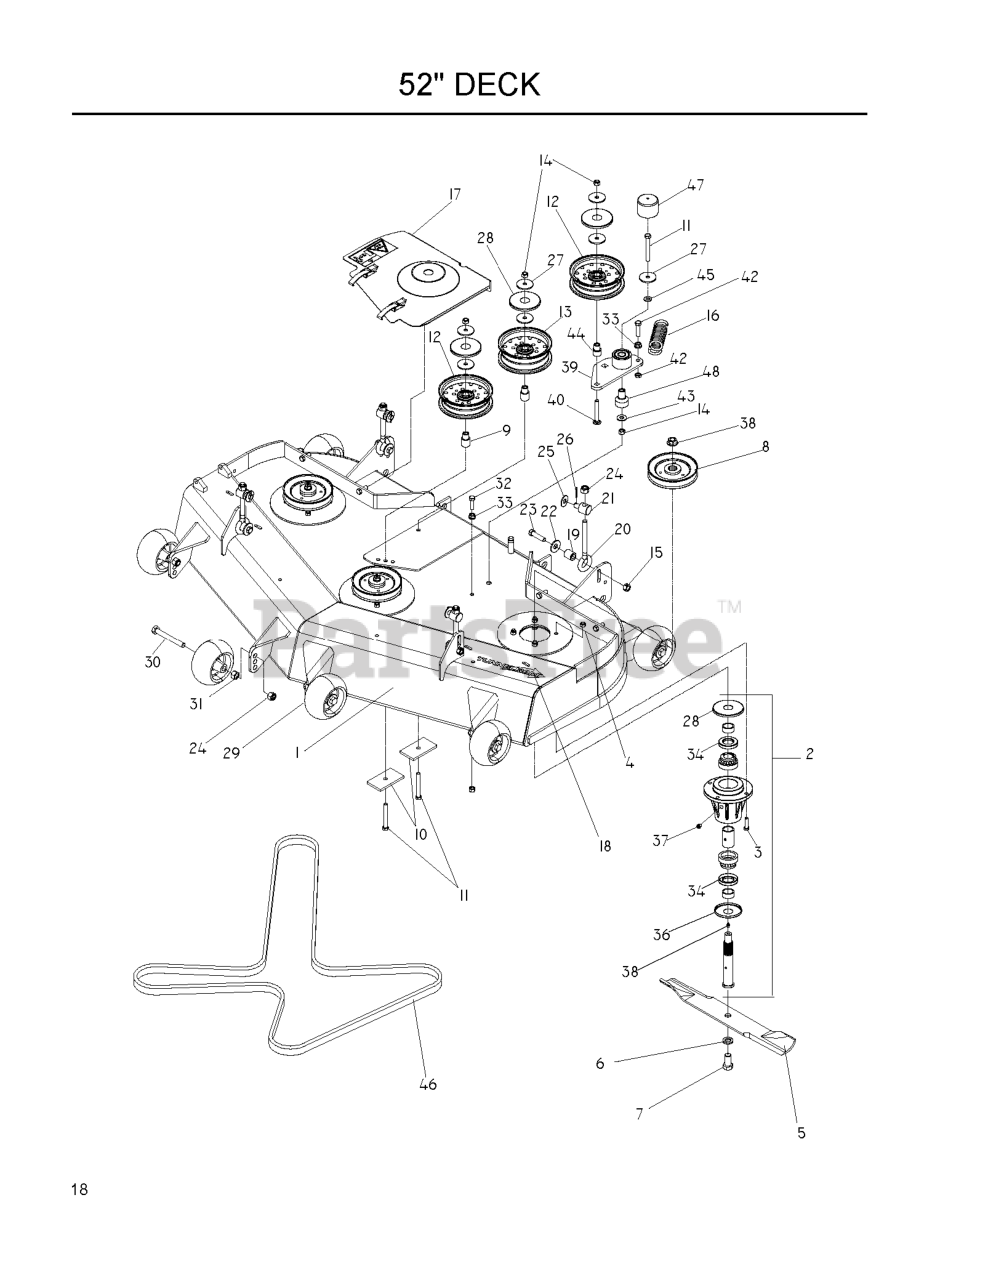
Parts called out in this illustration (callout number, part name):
1	DECK W/DECALS 52" HUS
2	HSG KIT 52/61 RIBBED
3	HCS 5/16C X 1 1/4
4	NUT 5/16 NYLOC
5	BLADE OEM 18"
6	LOCKWASHER 5/8
7	HCS 5/8F X 1 1/4
8	PULLEY, 52
9	IDLER BUSHING
10	SUPPORT PLATE
11	HCS 3/8C X 3
12	IDLER PULLEY
13	IDLER PULLEY (TALL)
14	NUT 3/8-16 NYLOC
15	NUT 7/16C CENTERLOCK
16	DECK SPRING
17	52" BELT SHIELD ASM - LH
17	52" BELT SHIELD ASM - RH
18	DECAL, TUNNEL RAM 8"
22	SPRING WASHER - .50
23	HCS 7/16 - 14 X 1 3/4
24	NUT 1/2-13 HEX NYLOC ZD
25	WASHER 1/2 FLAT
26	PIN COTTER 1/8 X 1 ZD
27	WASHER, 3/8 SPEC
28	TOP DUST CAP
29	GAUGE WHEEL
30	HCS 1/2-13 X 4 GR 5 ZD
31	NUT HEX 1/2
32	HCS 3/8C X 1 1/4 GR5
33	NUT 3/8C WHIZ
34	SHAFT SEAL
35	BOTTOM DUST CAP
36	PLUG-VENTED
38	NUT FLANGE 3/4-16
39	ARM-IDLER W/BRG
40	RHSNB 3/8-16 X 2.75
41	HCS 3/8-16 X 1-1/2
42	NUT 3/8-16 HEX JAM
43	WASHER 3/8 FLAT
44	BUSHING, IDLER
45	WASHER 3/8 SAE FLAT
46	PUMP BELT
47	CAP, VINYL
48	PIVOT, BEARING
